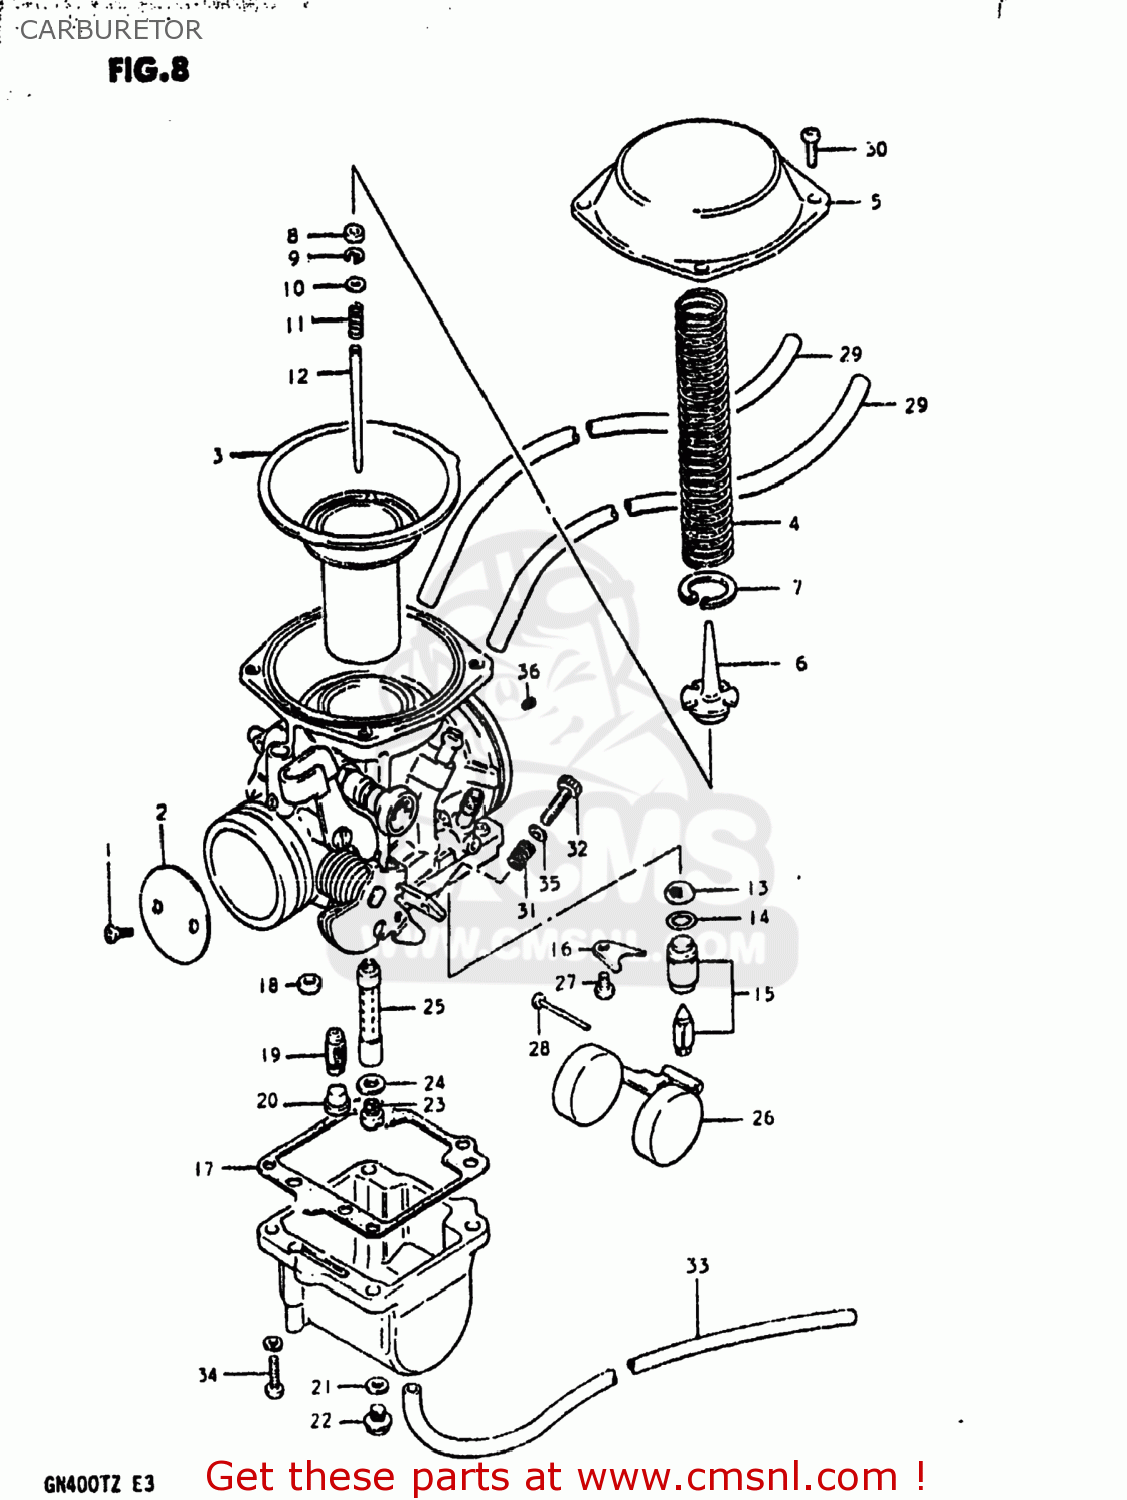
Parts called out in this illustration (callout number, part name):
1	SCREW
2	VALVE,THROTTLE (BUTTERFLY)
3	DIAPHRAGM
4	SPRING
5	COVER,DIAPHRAGM
6	HOLDER,GUIDE
7	E RING
8	RING
9	CLIP,NEEDLE
10	WASHER
11	SPRING
12	NEEDLE JET
13	FILTER
14	O RING
15	VALVE ASSEMBLY,NEEDLE
16	PLATE
17	GASKET,FLOAT CHAMBER (NAS)
18	GASKET (NAS)
19	JET,PILOT(42.5)
20	PLUG,NEEDLE JET
21	GASKET (NAS)
22	PLUG,DRAIN
23	JET,MAIN(132.5)
24	WASHER
25	JET,NEEDLE
26	FLOAT
27	SCREW 4X6
28	PIN,FLOAT
29	HOSE
30	SCREW
31	SPRING
32	SCREW,THROTTLE STOP
33	HOSE
34	SCREW
35	WASHER
36	JET
